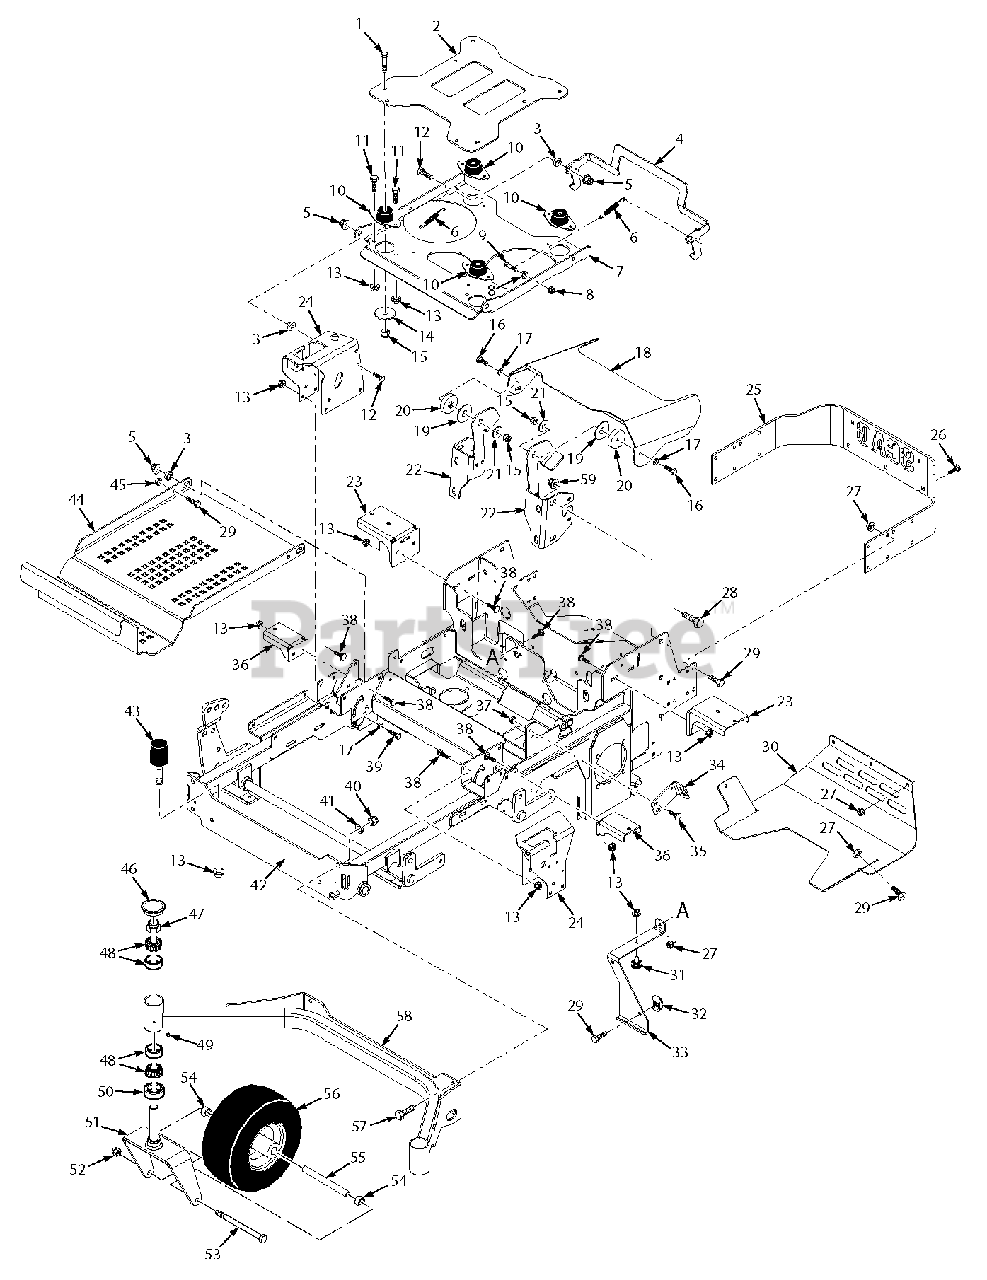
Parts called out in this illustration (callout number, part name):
1	Bolt, Hex Head 3/8-16 x 2-1/4"
2	Seat Plate w/decal
3	Bushing
4	Seat Latch
5	Nut, Elastic Flange 3/8-16
6	Spring, Seat Latch
7	Plate, Seat Mounting w/decals
8	Nut, Serrated Flange 1/4-20
9	Bolt, Hex Head 1/4-20 x 1-1/4"
10	Isolator, Seat
11	Bolt, Hex Head 5/16-18 x 3/4"
12	Bolt, Hex Head 3/8-16 x 1-1/4"
13	Nut, Hex Serr. Flng 5/16-18
14	Flatwasher, 3/8-.406 x 2.25 x .1875
15	Nut, Elastic Stop 3/8-16
16	Bolt, Hex Head 3/8-16 x 1-3/4"
17	Flatwasher, 3/8-.391 x .938 x .105
18	Hood Assembly
19	Disk, Anti-Friction
20	Spacer, Hood
21	Flatwasher, 3/8-.406 x 1.50 x 7 Ga.
22	ROPS Mount, RH
22	ROPS Mount, LH
23	Mounting Bracket, Fuel Tank Rear
24	Control Plate w/decal, RH
24	Control Plate w/decal, LH
25	Bumper, Rear
26	Bolt, Carriage 3/8-16 x 1"
27	Nut, 3/8-16 Serr. Flange
28	Bolt, Hex Head 1/2-13 x 1-1/4"
29	Bolt, Hex Head 3/8-16 x 1"
30	Plate, Skid
31	Bumper, Rubber
32	U-Nut, 3/8-16
33	Battery Hold Down
34	Mounting Bracket, Neutral Switch
35	Bolt, Carriage 1/4-20 x 3/4"
36	Mounting Bracket, Fuel Tank Front
37	Nut, Flanged Elastic Stop 1/4-20
38	Bolt, Carriage 5/16-18 x 3/4"
39	Bolt, Hex Head 3/8-16 x 1-1/2"
40	Nut, Elastic Stop 7/16-14
41	Lockwasher, 7/16" Spring
42	Main Frame Assembly w/decals (48"/52")
42	Main Frame Assembly w/decals (61")
43	Rubber Isolator
44	Footplate
45	Nut, Jam 3/8-16
46	Cap, Grease
47	Nut, Elastic Stop 1.0"-14
48	Bearing Set
49	Plug, 1/4-28
50	Seal, 2.0" OD x 1.625" ID
51	Yoke, Front Caster Wheel (48"/52")
51	Yoke, Front Caster Wheel (61")
52	Nut, Hex Elastic Stop 1/2-13
53	Bolt, Hex Head 1/2-13 x 7-1/2" (48"/52")
53	Bolt, Hex Head 1/2-13 x 9-1/2" (61")
54	Spacer, Caster Wheel
55	Sleeve (48"/52")
55	Sleeve (61")
56	Caster Wheel Assembly (48"/52")
56	Caster Wheel Assembly (61")
57	Bolt, Hex Head 7/16-14 x 1-1/4"
58	Caster Support Weldment (48"/52")
58	Caster Support Weldment (61")
59	Nut, 1/2-13 Flange Elastic Stop
